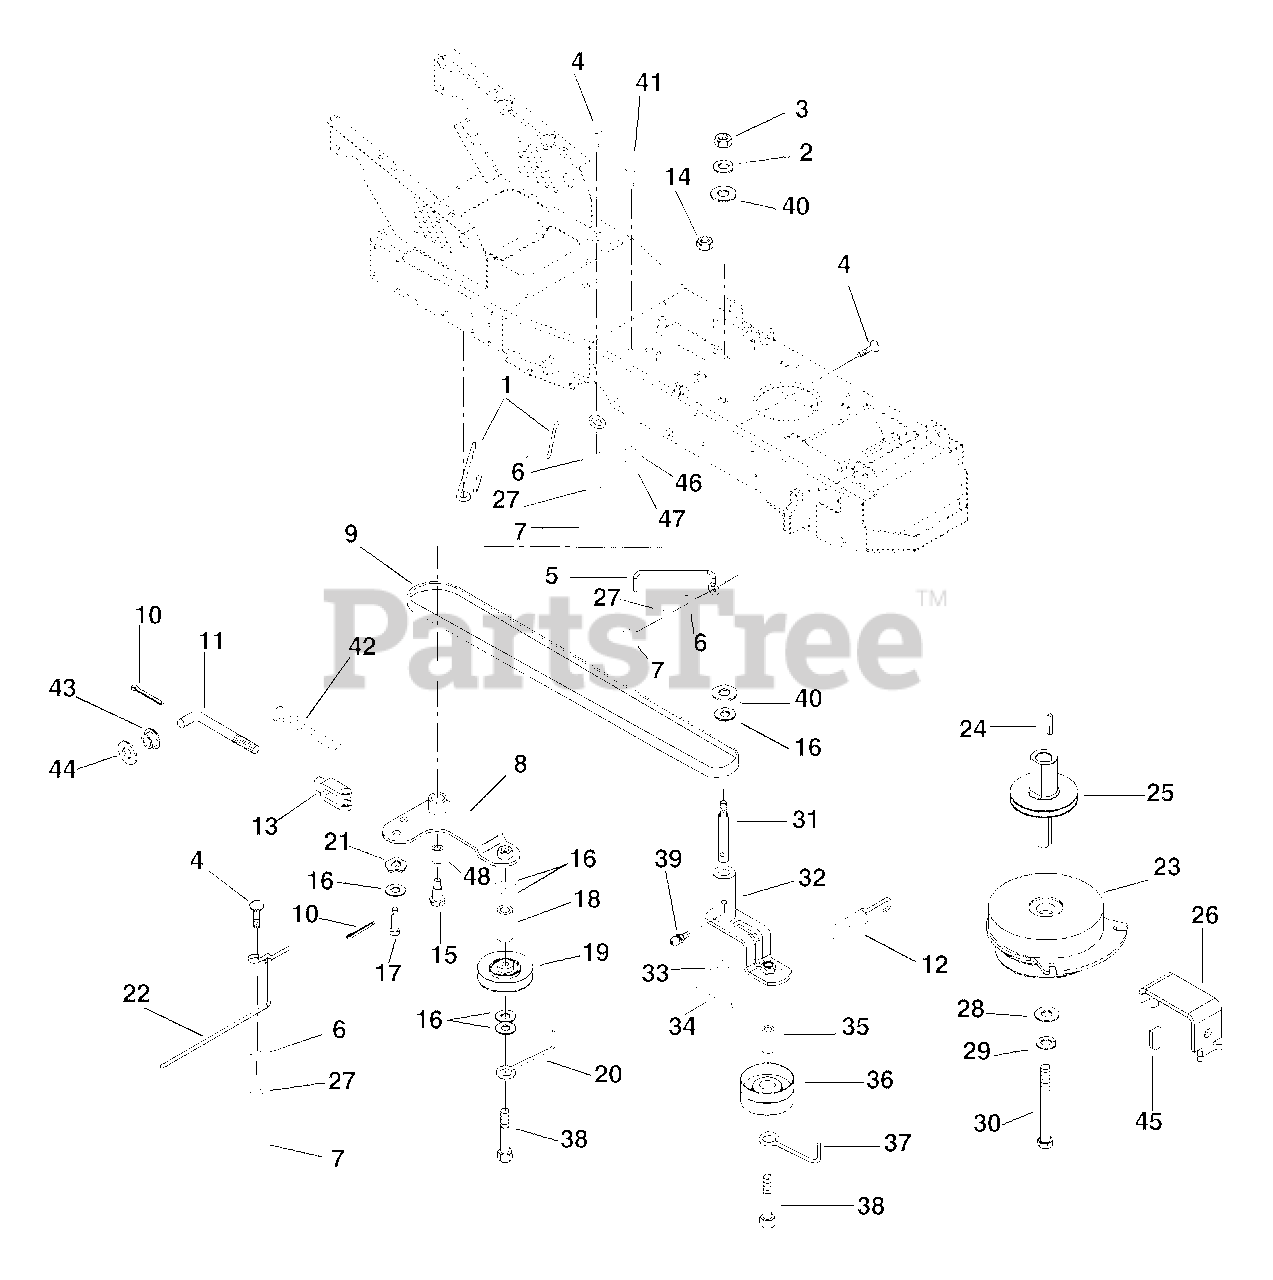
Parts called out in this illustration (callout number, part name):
1	BELT FINGER
2	@WSHR-LK .38X.094 REG YWZC
3	@NUT-HEX .38-16 YWZC
4	BLT-RDHDSQSHK.31-18X.75 GR2 YW
5	BELT FINGER
6	@WSHR-FL-STL.344X.688X.065YWZC
7	@NUT-HEX .31-18 YWZC
8	IDLER PIVOT ARM
9	V-BELT, 4L-WRAPPED
10	@PIN-CTR .09X.75 EXTPRSQCT YWZ
12	SPRING, EXT
13	YOKE, .312-24 X 2.25
14	@NUT-LK-CTR .38-16 YWZC
15	BLT-SHLDR .38-16X1.25
16	WSHR-FL-STL .390X.75X.125 YWZC
17	PIN-CLEV .312X.822 HDND PL
18	TUBE .380 X .625 X 1.360
19	IDLER-V 3X.38
20	FINGER - BELT
21	WAVE WASHER .531X.781X.125FH
22	BELT FINGER - CENTER
23	CLUTCH, ELECTRIC - WARNER
24	KEY-SQ .25 X 1.25 X .25 SAE
25	SHAFT, EXTENSION
26	ANCHOR, CLUTCH
27	WSHR-LK .312X.097 HVY YWZC
28	WSHR-FL-STL.463X1.375X.25 YWZC
29	WSHR-LK .438X.133 HVY YWZC
30	BLT-HEX .44-20X5.50 GR5 YWZC
31	SHOULDER STUD
32	ARM - IDLER PIVOT
33	WSHR-FL-STL .52X.827X.062 YWZC
34	@PIN-CTR .18X1.25 EXTPRSQCT YZ
35	SPACER-.38 X .62 X 2.12
36	IDLER, FLAT 3.25 X .38
37	FINGER - BELT
38	@BLT-HEX .38-16X4.00 GR5 YWZC
39	FTG-LUBE .25-28X.256 YWZC
40	@WSHR-FL-STL.438X1.00X.083 YWZ
41	BLT-RDHDSQNK .31-18X1.0 SHTYZ
42	SG-TENS .105X.85X5.00 WLD 40
43	BSHG-FLG .320X.620X.312 NY
44	WSHR-FL-STL .505X.880X.072 YWZ
45	GRIP .062 X .375 X 1.000 RE
46	@NUT-LK-NYL .312-18 YWZC
47	@NUT-LK-CTR .31-18 YWZC
48	BSHG-SLV .328X.50X.75
